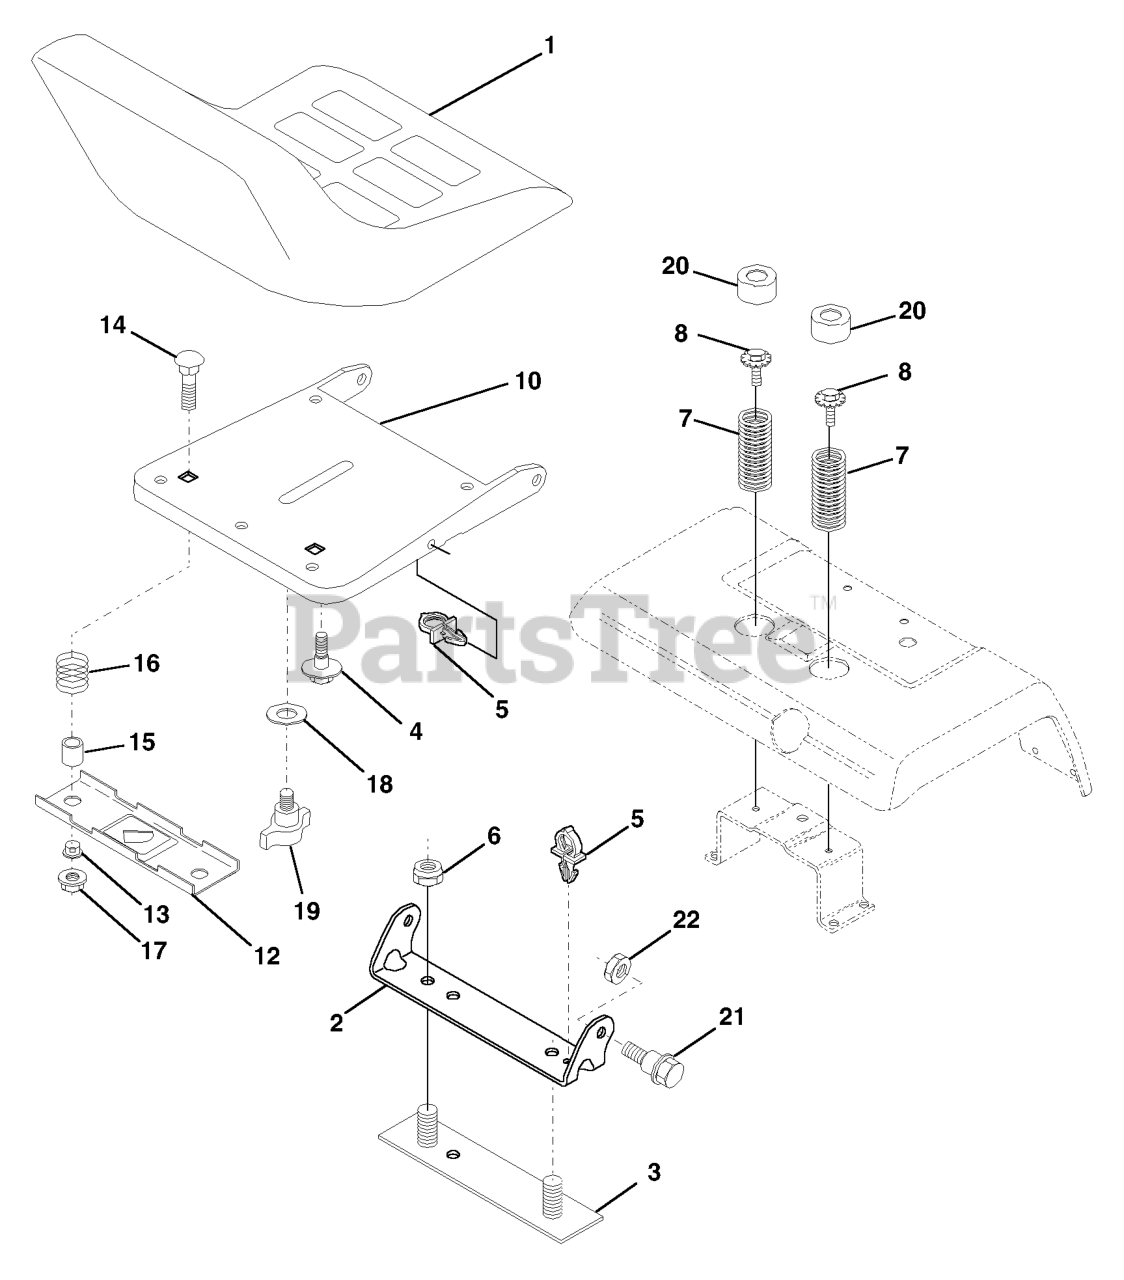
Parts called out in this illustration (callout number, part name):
1	SEAT
2	SEAT PIVOT BRKT
3	STRAP
4	BOLT,SHOULD
6	NUT
7	SPRING COMPRESSION
8	BOLT HEX WASHER HD 5/16-18
10	PAN, SEAT
12	BRKT SWITCH
14	BOLT.ROUND.HEAD.SQUARE.NECK
15	SPACER SPLIT
16	SPRING COMPRESSED
17	NUT T
19	KNOB.SEAT.ADJ.WINGNUT
20	CAP SPRING
21	BOLT SHOULDER 5/16-18
22	LOCKNUT
